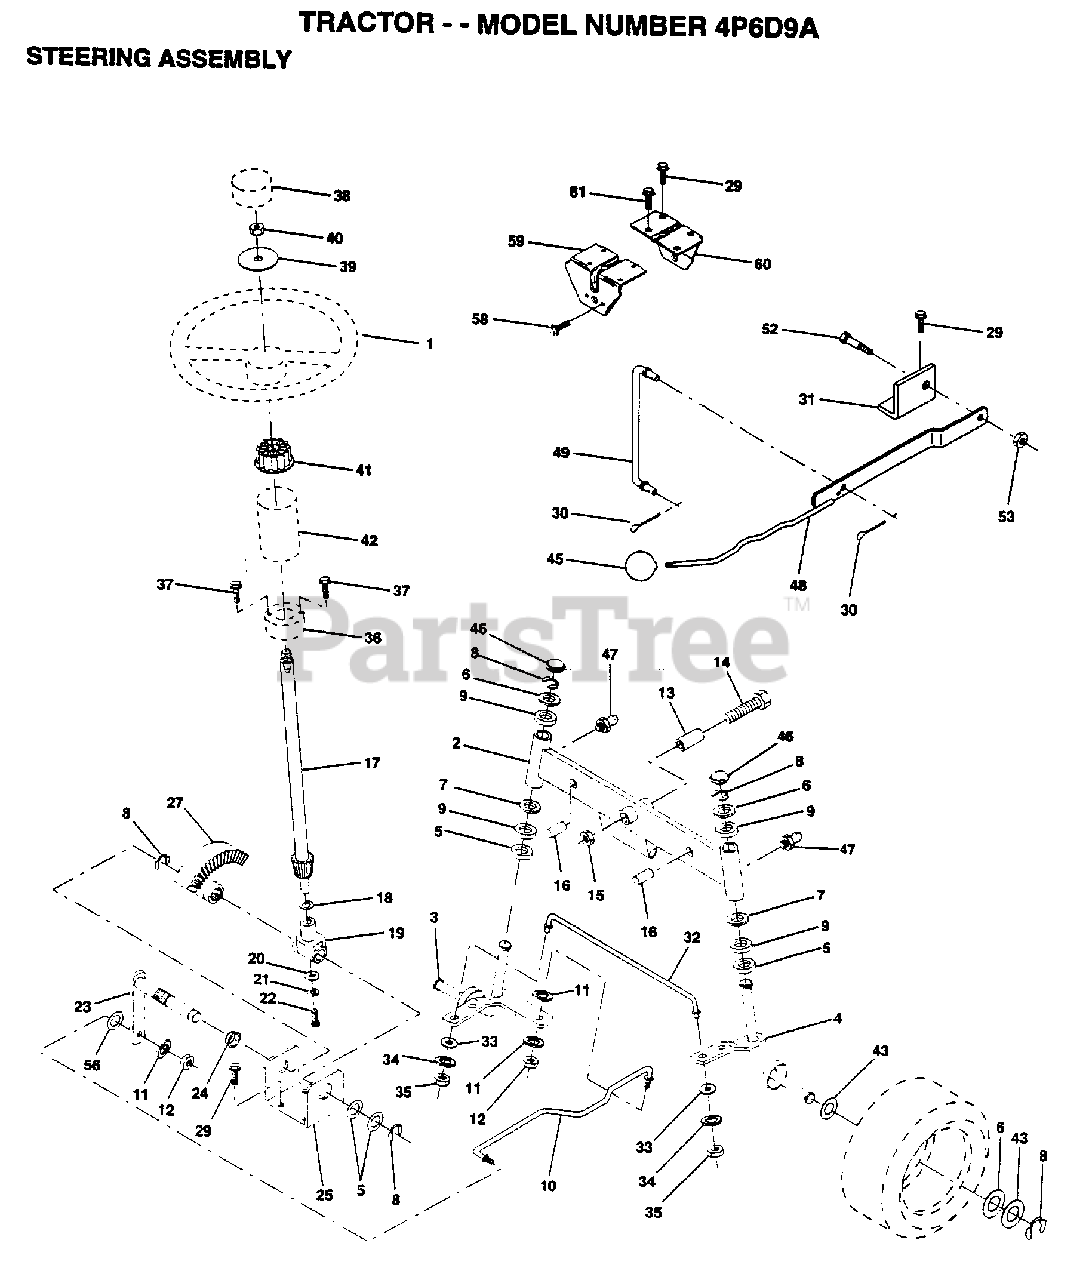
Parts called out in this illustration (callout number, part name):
2	AXLE ASM FRONT
5	WASHER .T
6	WASHER
7	WASHER
8	RING
9	COL. SRTG. BEAR.
11	LOCKWASHER
13	BEARING
14	BOLT LT
15	"NUT-LOC,FLANGE LT"
16	AXLE PIN
17	STEERING SHAFT
18	THRUST WASHER
19	SUPPORT.SHAFT
21	LOCKWASHER
22	"SCREW,SPECIAL"
24	NYLINER T
25	"BRKT,STEERING"
27	GEAR SECTOR
29	SCREW
30	COTTER PIN
31	BRKT.PVT.MAN.LVR.
32	ROD.TIE.19.75
33	WASHER M
34	LOCKWASHER
35	NUT.LOCK.5/16-24
36	BUSHING.STRG.3/4
37	SCREW.10-24X1/2
38	ST WHL INSERT CAP
39	WASHER
41	ADAPTER LT
42	BOOT SHAFT STEER
43	WASHER
45	KNOB T (1/2-HOLE)
46	CAP
47	ZERK M
48	LEVER.CLUTCH.MOWR
49	LINK CLTCH W/NUTS
52	"BOLT, SHOULDER LT"
56	WASHER
58	SCREW LT
59	SUPPORT-SADDL T
60	SUPPORT.SADDLE.FT
61	SCREW SPECIAL
